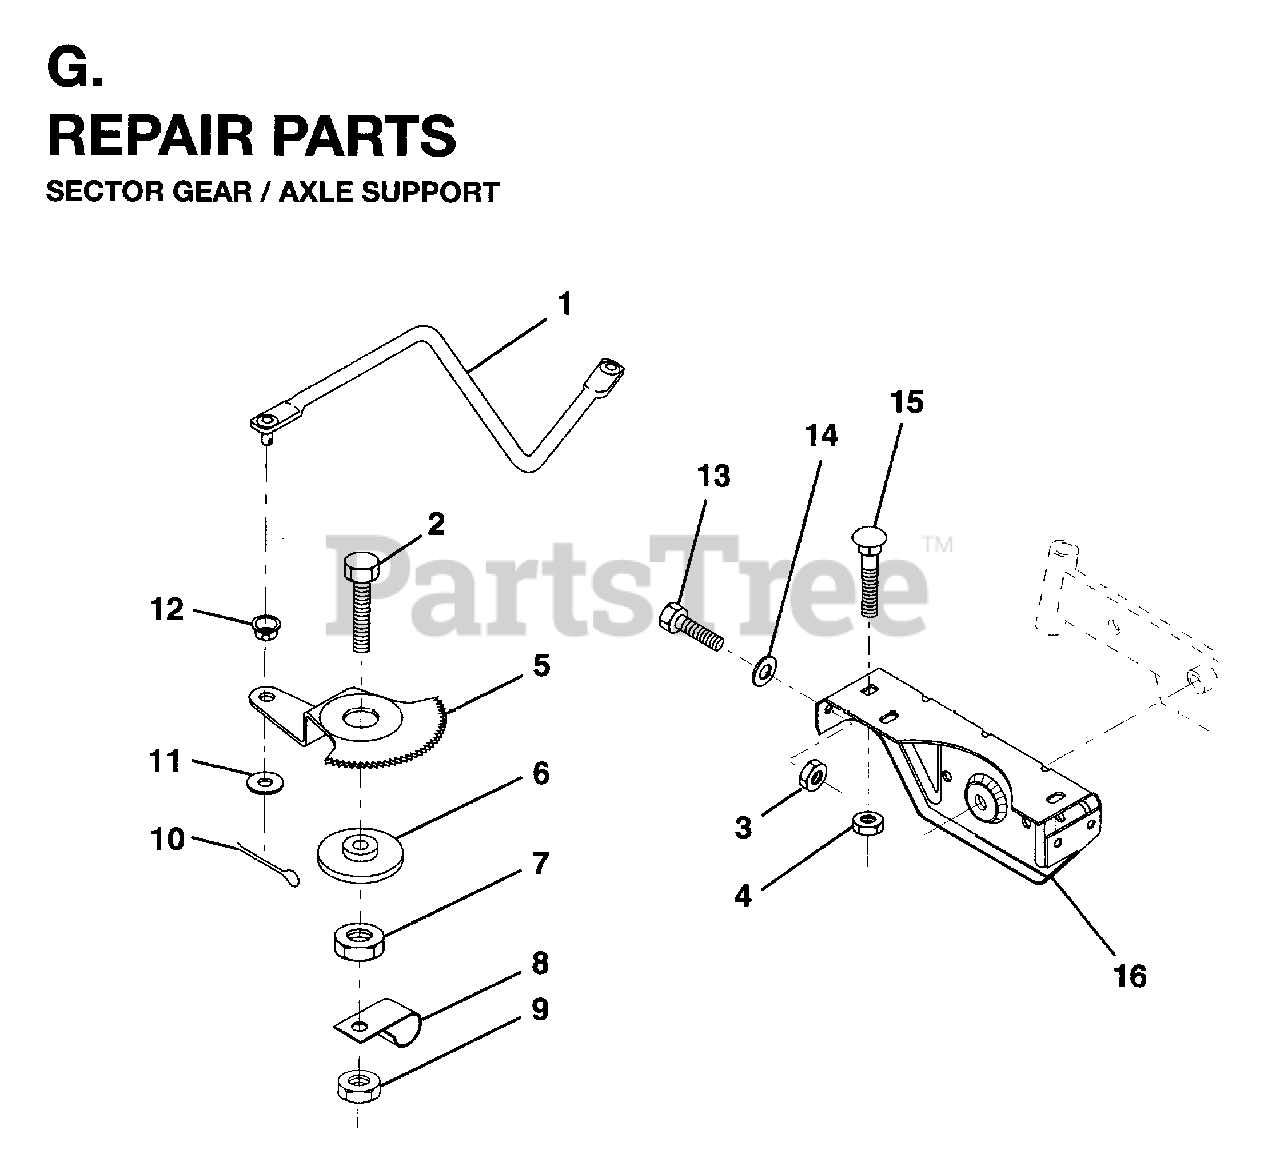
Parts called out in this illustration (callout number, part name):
1	LINK DRAG
3	LOCKNUT
4	LOCKNUT
5	GEAR SECTOR
7	NUT LTV
8	CLIP INSULATOR
9	NUT LTV
10	COTTER PIN
11	WASHER
12	BUSHING.DRAGLINK
13	BOLT
14	WASHER - 25X8.5X2.3
16	SUPPORT/AXLE FRONT
